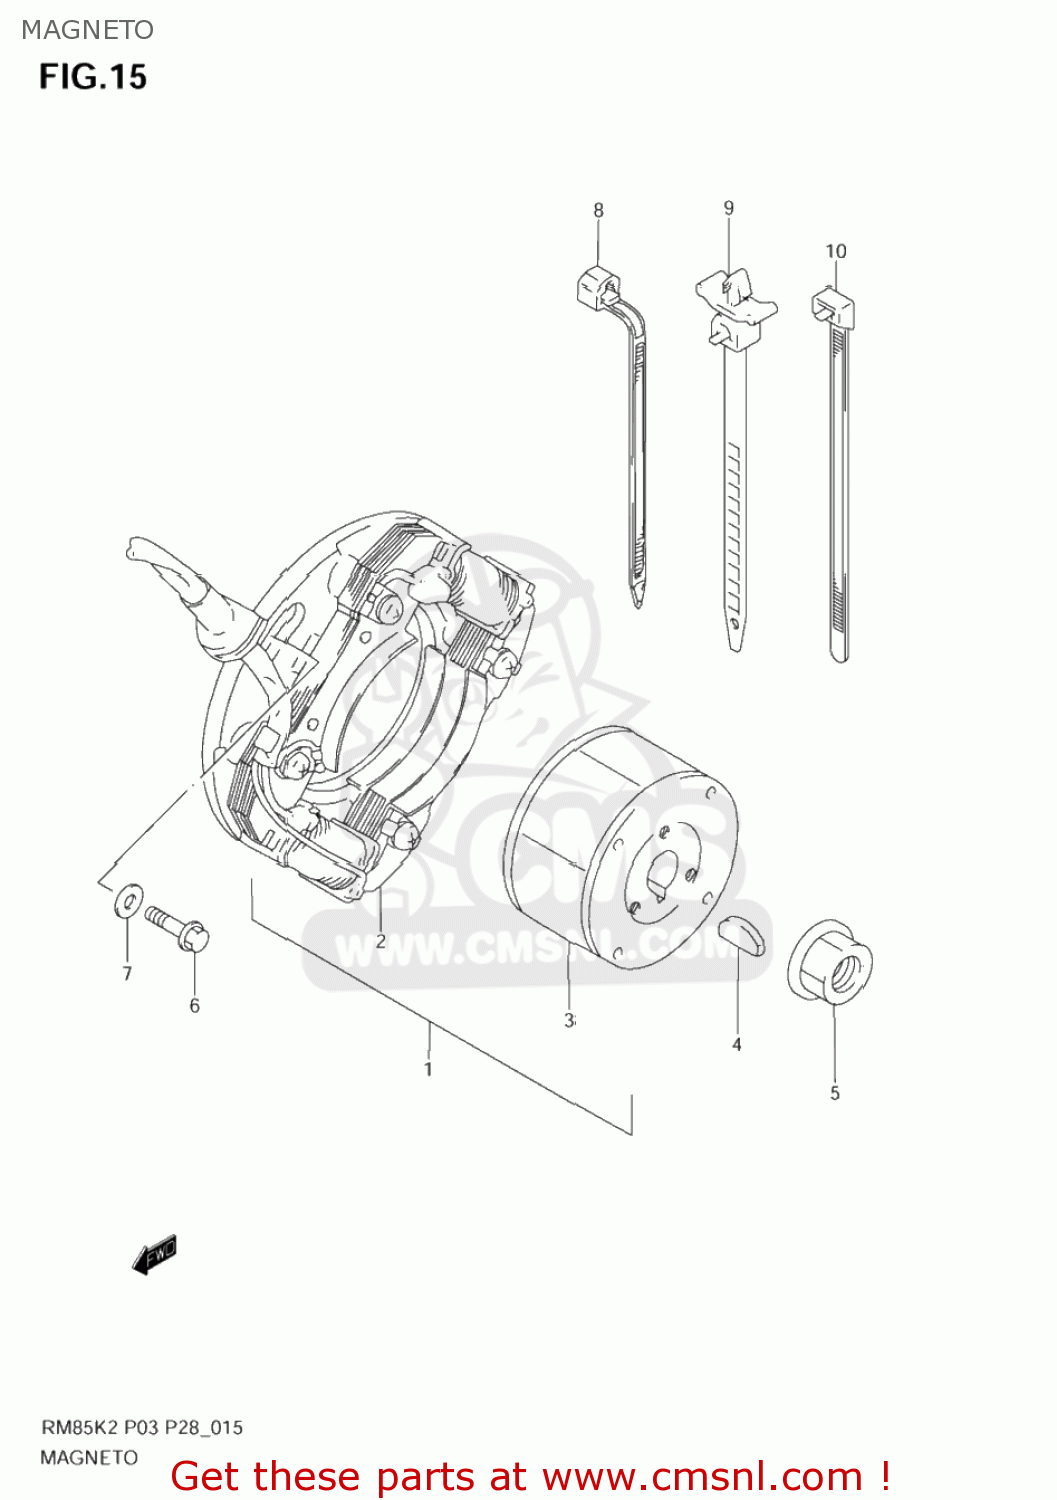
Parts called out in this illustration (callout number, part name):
1	MAGNETO ASSEMBLY
2	STATOR
3	ROTOR
4	KEY
5	NUT
6	BOLT,6X20
7	WASHER
8	CLAMP(L:125)
9	CLAMP(L:120)
10	CLAMP(L:150)
